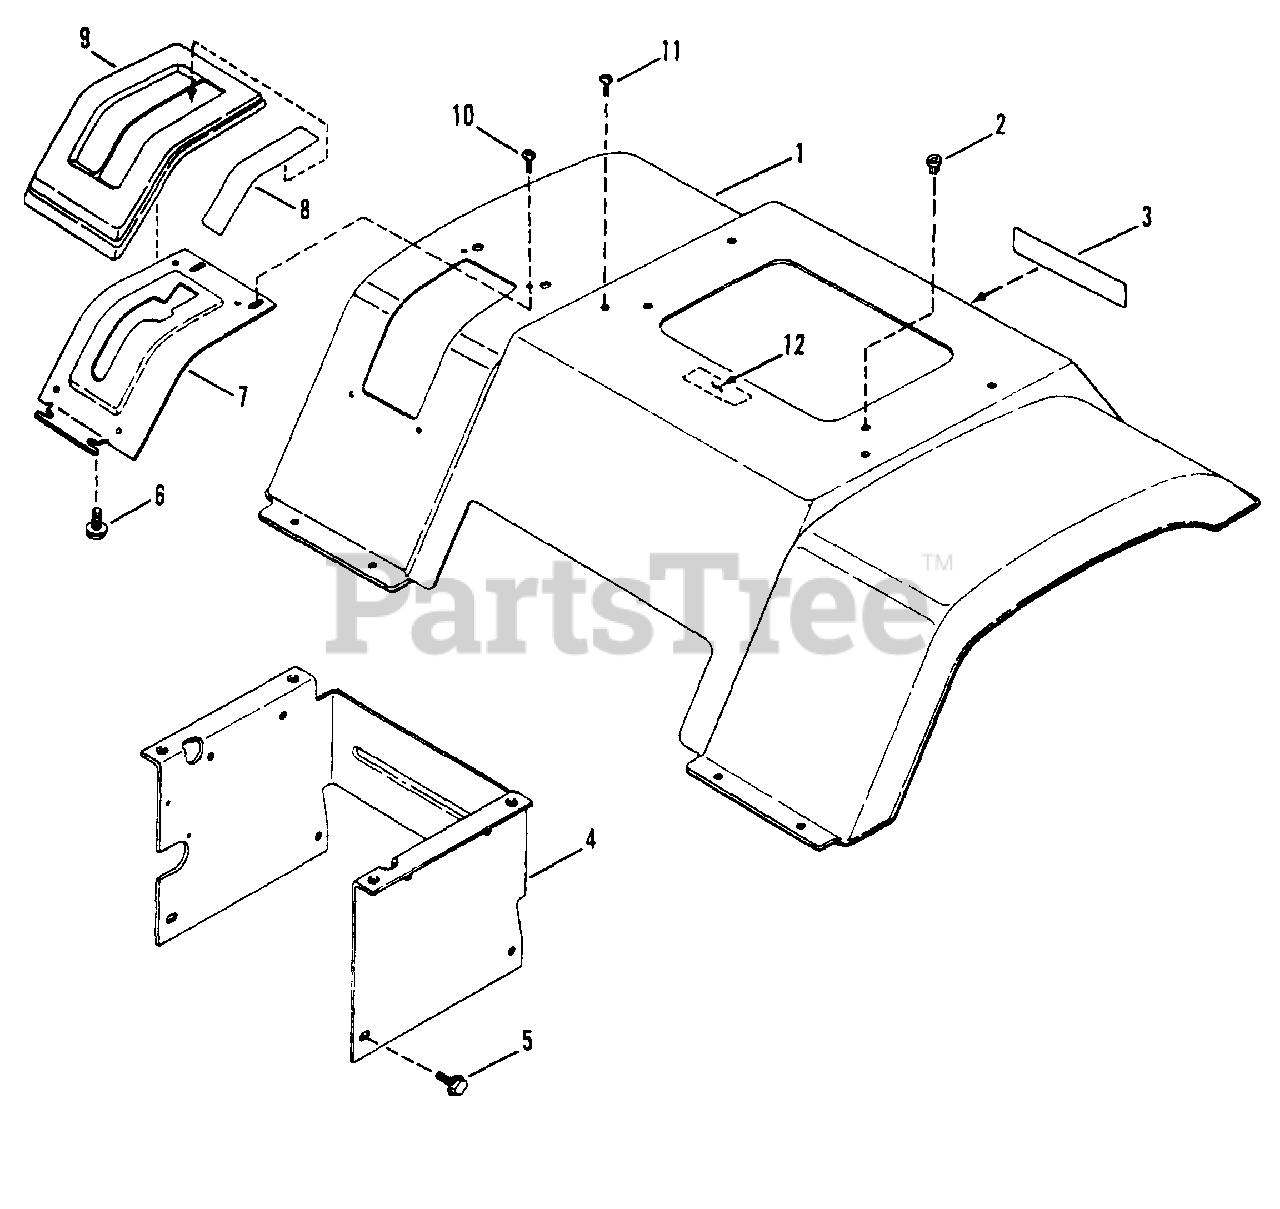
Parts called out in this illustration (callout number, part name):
1	PAN, Seat (Fender)
2	RIV-NUT, 5/16-18
3	DECAL-SNAPPER, 7.28" Molded Logo, White Ltr's. & Stripe
3	DECAL-SNAPPER, 7.28" Molded Logo, Silver Ltr's., Teal Stripe
4	SUPPORT, Fender
5	SCREW, 5/16-18 x 5/8" Hex Washer Head, Self-Tapping
6	SCREW, #10-16 x 1/2' Hex Washer Head, Self-Tapping
7	DETENT, Gear Shift
8	DECAL, Shift Cover, 5 Speed
9	COVER, Shift
10	SCREW, 1/4-20 x 5/8" Truss Head, Torx
11	SCREW, 5/16-18 x 5/8" Truss Head, Torx
12	DECAL - CAUTION, Battery Location
